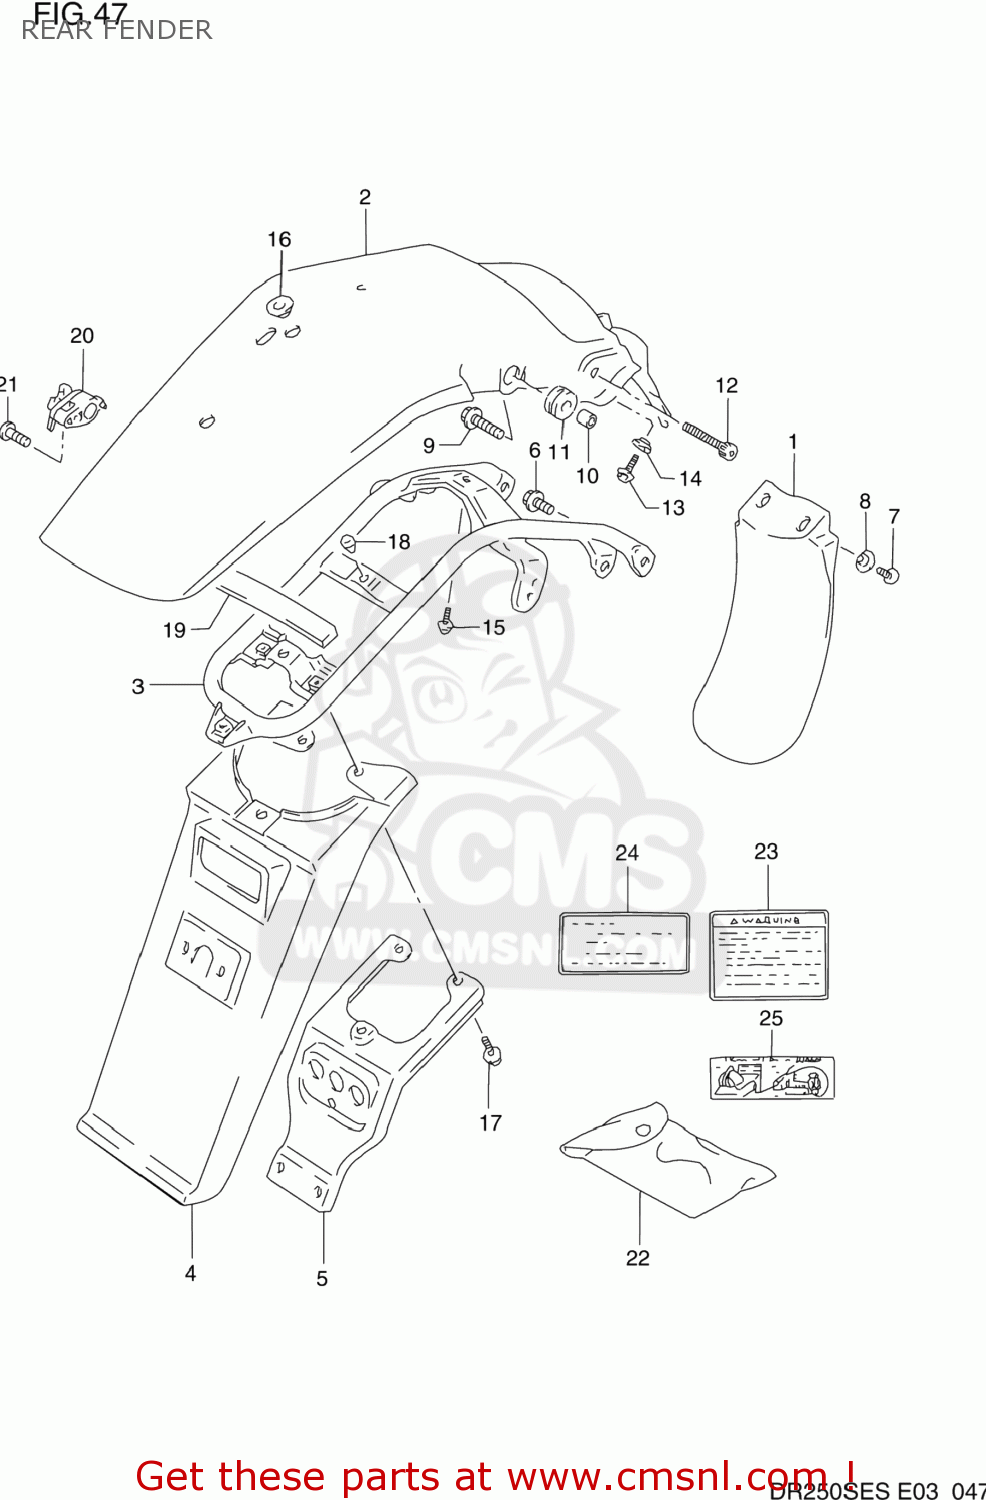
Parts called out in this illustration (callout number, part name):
1	BODY,RR FENDER FR
2	FENDER,REAR
3	REINF,RR FENDER
4	EXTENSION,RR FENDER
5	REINFORCMENT,REAR FENDER
6	BOLT
7	SCREW 6X12
8	WASHER
9	BOLT(8X30)
10	SPACER (8.8X12X7)
11	CUSHION
12	BOLT(8X30)
13	BOLT
14	WASHER
15	BOLT
16	WASHER(14.2X26X1.2)
17	BOLT
18	CUSHION
19	CUSHION,REAR FENDER
20	LOCK SET,HELMET
21	SCREW
22	TOOL SET
23	LABEL
24	LABEL,STARTING CAUTION
25	LABEL,PIPING DIAG
26	LABEL (TIRE AIR PRESSURE)
27	MANUAL, OWNER'S
